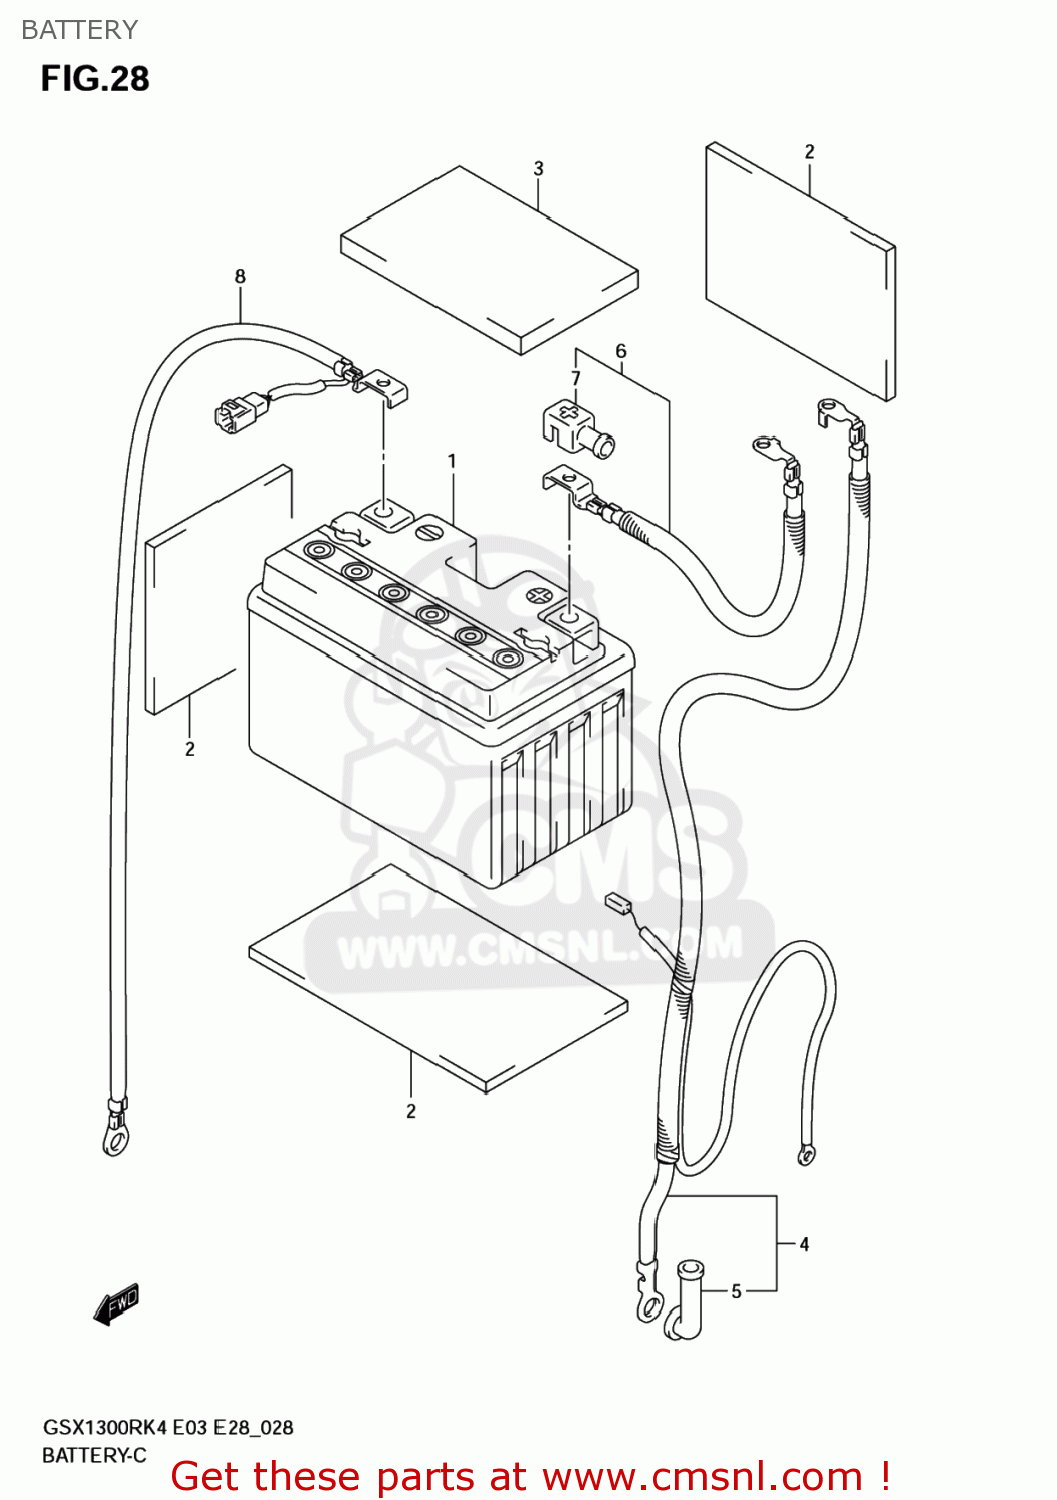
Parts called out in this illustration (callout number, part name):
1	BATTERY(YT12A-BS,12V10.5AH)
2	PROTECTOR(170X95X3.0)
3	PROTECTOR,BATT
4	WIRE,STARTER MOTOR
5	CAP,STARTER MOTOR LEAD
6	WIRE,BATTERY PLUS
7	CAP,BATTERY PLUS
8	WIRE,STARTER MOTOR
